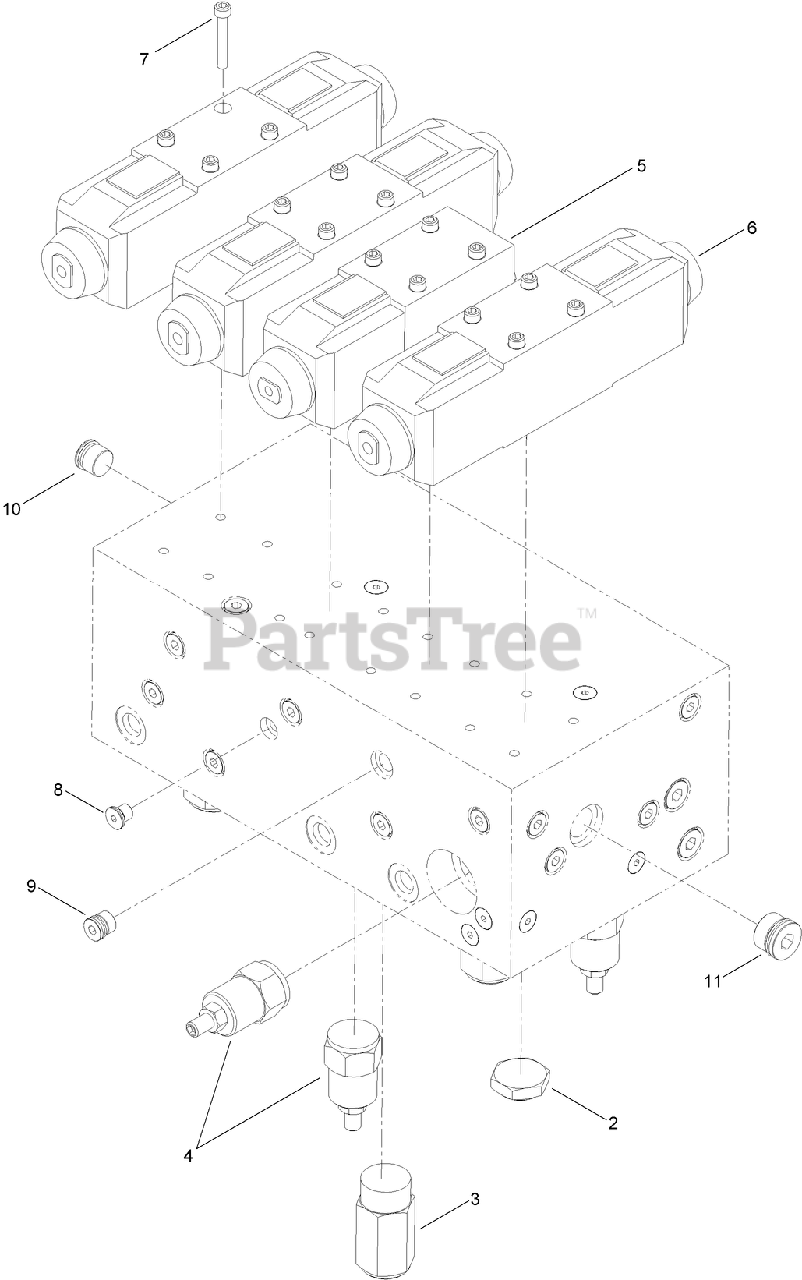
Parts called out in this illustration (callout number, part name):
2	VALVE-CHECK
3	VALVE-RELIEF
4	VALVE-COUNTERBALANCE
5	VALVE-CONTROL, DIRECTIONAL
6	VALVE-CONTROL, DIRECTIONAL
7	SCREW-HSH
8	PLUG-LEAK, ZERO
9	PLUG-HYD
10	PLUG-HYD
11	PLUG-HYD
